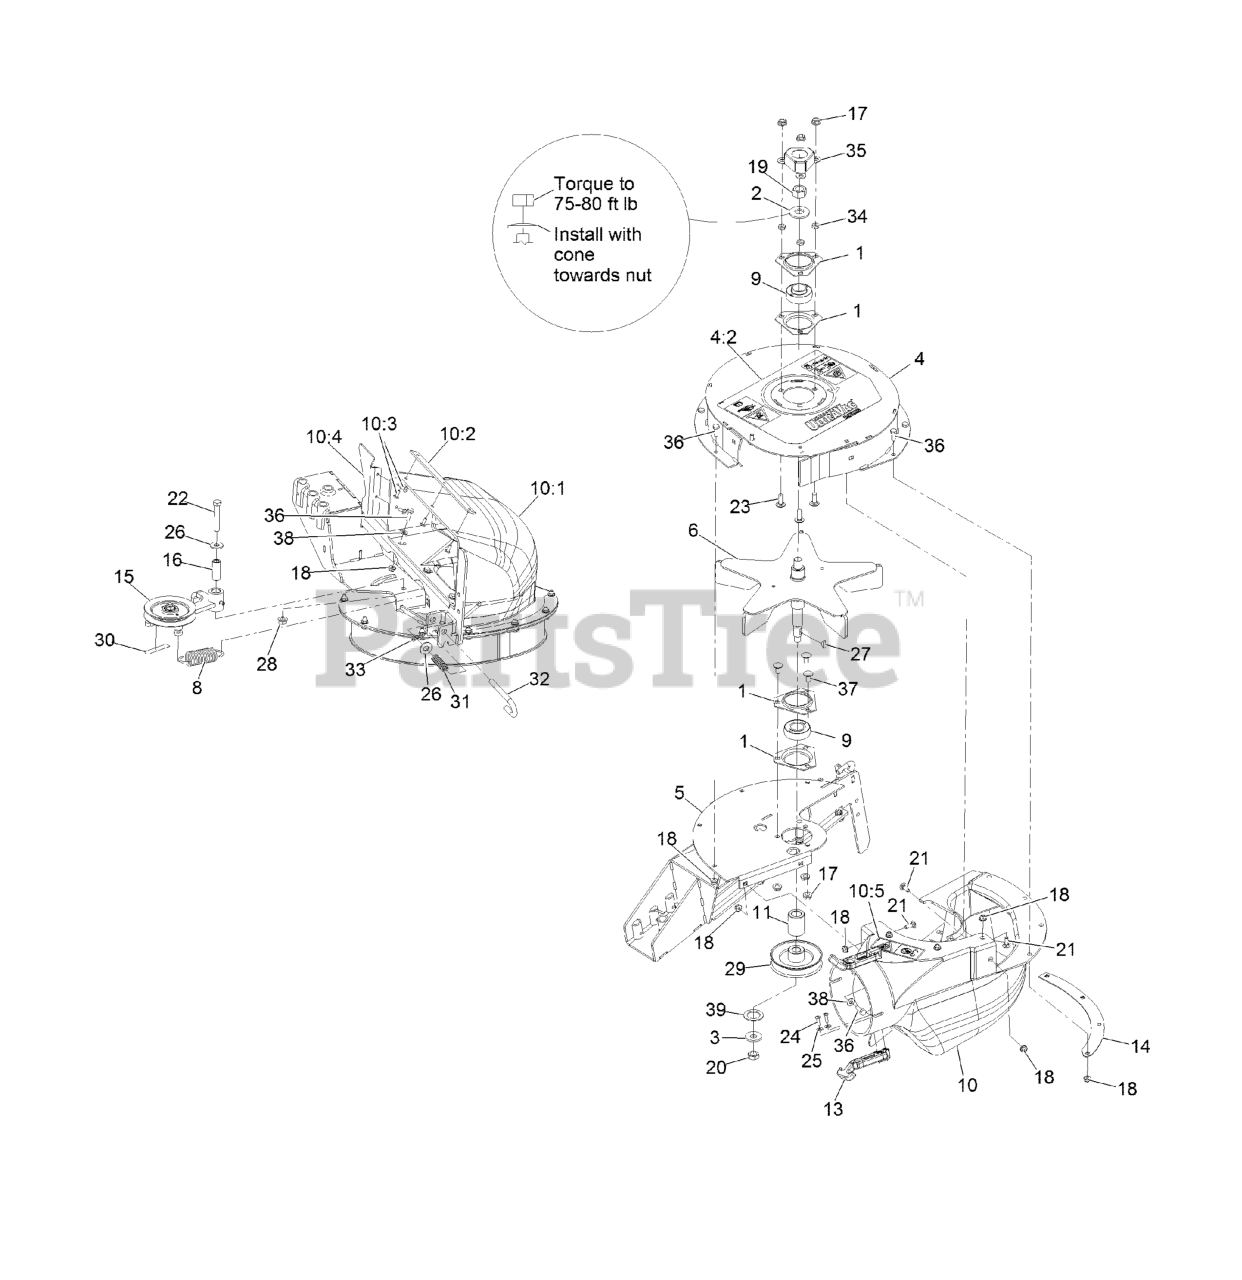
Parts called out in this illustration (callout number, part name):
1	HOUSING-FLANGE
2	WASHER-SPRING
3	WASHER-SPRING
4	UPPER HOUSING W/DECAL
4:2	Decal-Blower Warning
5	BLOWER FRAME ASM
6	IMPELLER
8	SPRING-IDLER
9	BEARING
10	BLOWER CHUTE ASM
10:1	CHUTE-BLOWER, SMALL
10:2	PLATE-REINFORCEMENT
10:3	RIVET-BLIND
10:4	PLATE-FILLER
10:5	Decal-Blower-Impeller Hazard
13	LATCH-RUBBER
14	PLATE-BACKING
15	ASM, Idler
16	BUSHING
19	NUT-HEX
20	NUT-JAM
21	BOLT-CARR
22	SCREW-HH
23	BOLT-CARR
24	SCREW-PPH
25	WASHER-FLAT
26	WASHER-FLAT
27	KEY-WOODRUFF
28	NUT-HHF, WHIZ
29	SHEAVE-BLOWER
30	DECAL-WARNING
31	SPRING-COMPRESSION
32	PIN-LATCH
34	NUT-JAM
35	COVER-NUT
36	SCREW-HH
37	SCREW-CARR
38	WASHER-FLAT
39	WASHER-SPACER
